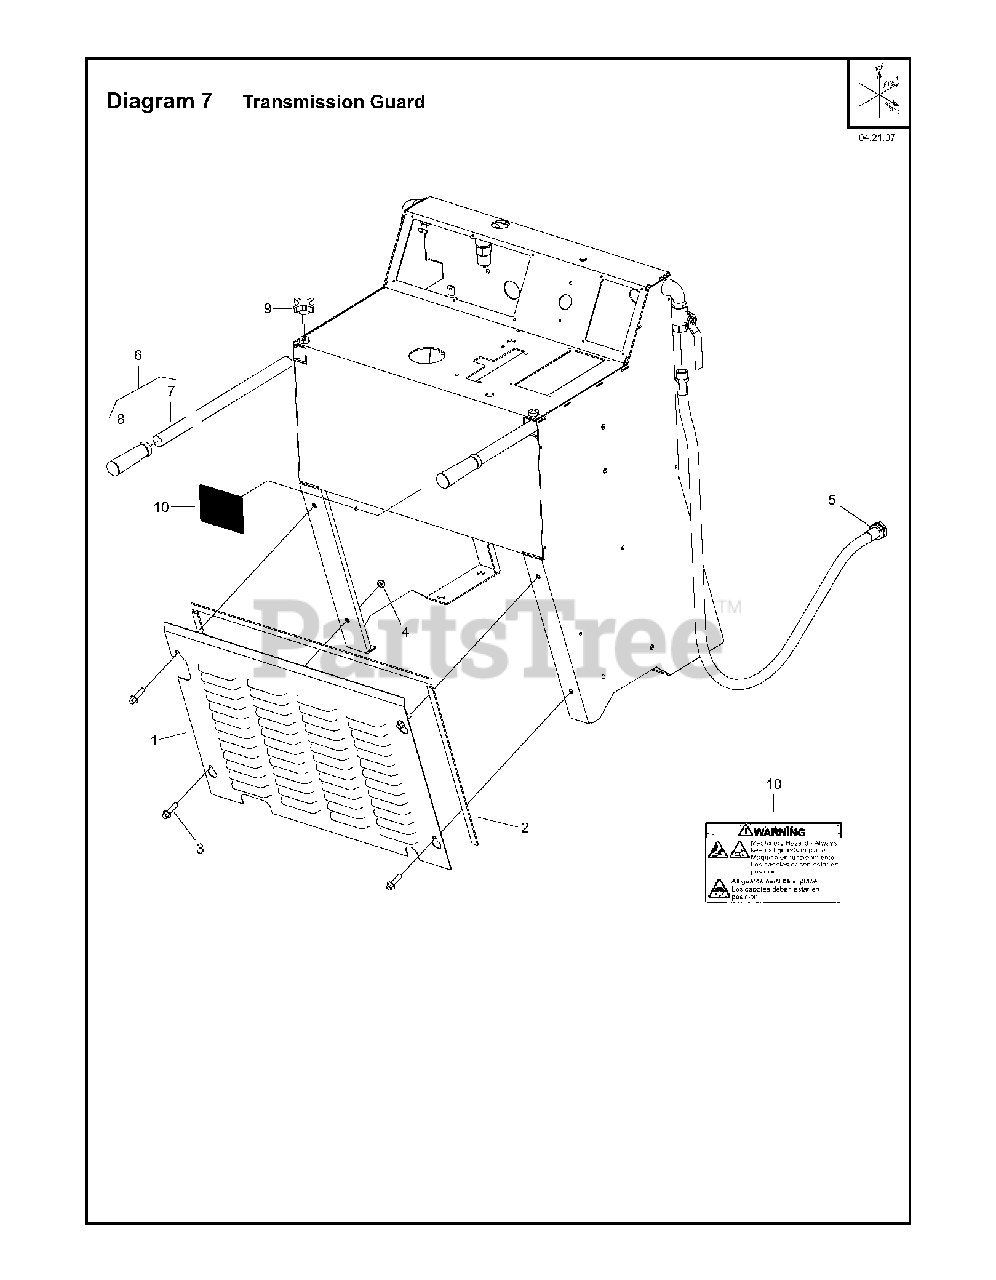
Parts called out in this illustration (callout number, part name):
2	STRIP. RUBBER SPONGE
3	FHCS. M8 x 1.25 x 30mm FT
4	LOCKNUT. FIBER M8 DIN 985 Z/P
